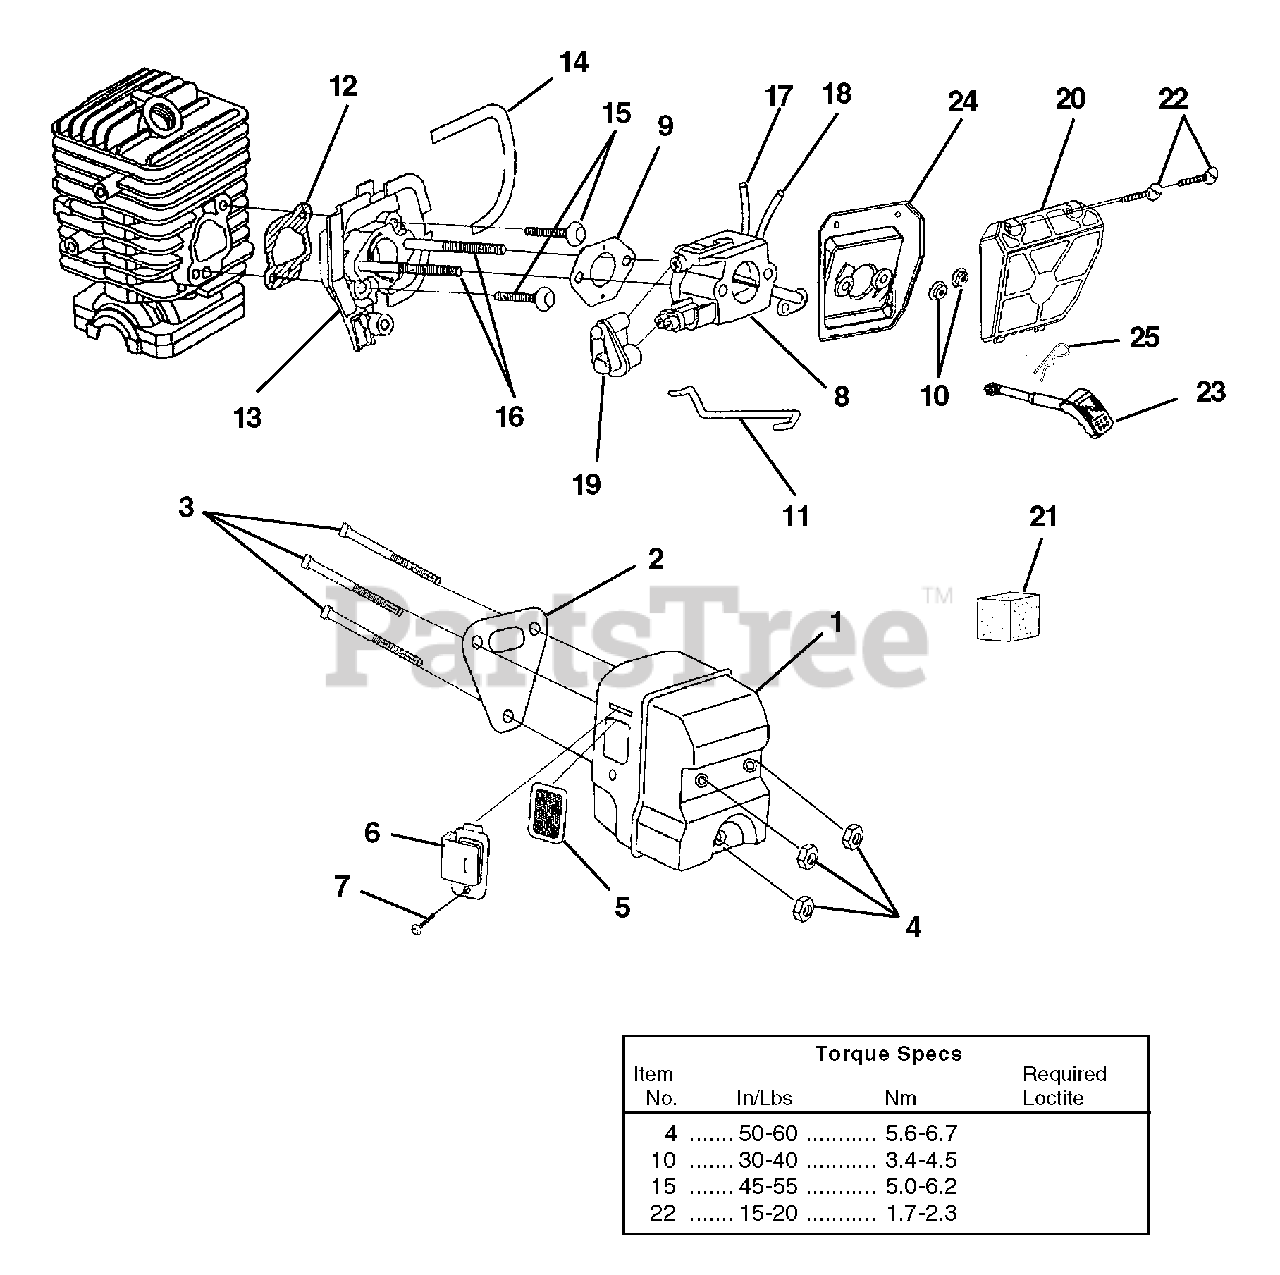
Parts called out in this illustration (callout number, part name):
1	Muffler Kit
2	Muffler Gasket
3	Screw-Square Hd.
4	Nut-Locking Hex (10-32)
5	Screen, Spark
6	Deflector, Muffler
7	Screw (8-32 x .312)
8	Carburetor Assembly
9	Carburetor Gasket
10	Flange Nut (10-24)
11	Throttle Wire
12	Gasket, Heat Dam
13	Carburetor Spacer
14	Seal, Heat Dam
15	Screw, Truss Hd. Taptite (10-24 x 7/8")
16	Screw, Carburetor
17	Fuel Line (Tank to Carburetor 8 1/2")
18	Fuel Line (Carburetor to Purge Bulb 4")
19	Carburetor Grommet
20	Air Filter Cover
21	Pre Filter (In engine housing)
22	Screw-Slotted Pan Hd. (8-16 x 5/8")
23	Rod, Choke
24	Air Filter Plate
25	Spring Clip (Choke Rod)
